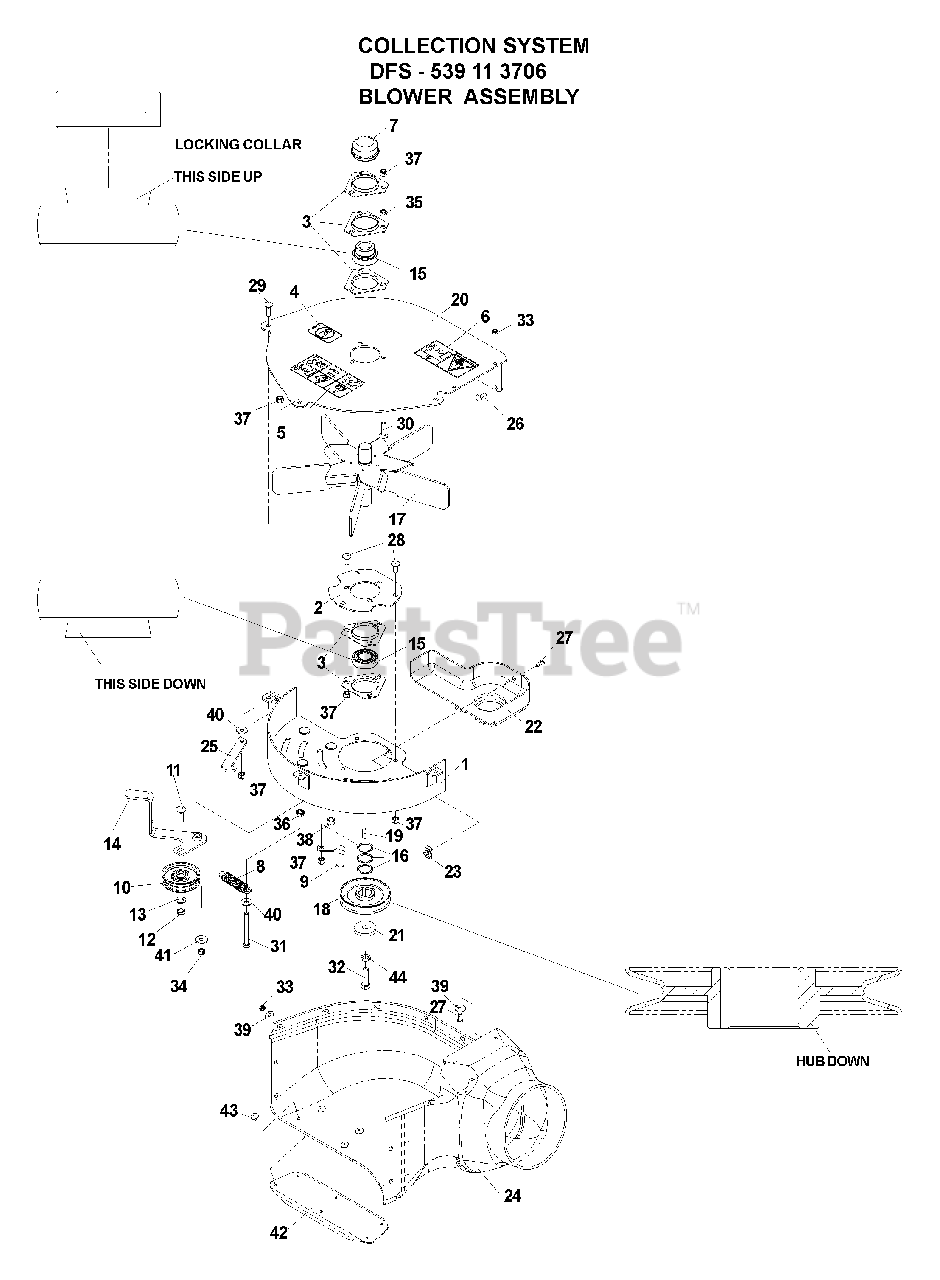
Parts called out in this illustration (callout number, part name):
1	FLOOR WELDMENT
2	BEARING PLATE
4	DECAL, NO STEP
5	DECAL, WARNING
6	DECAL, SERVERING
7	GREASE CAP
9	BELT GUIDE
11	RHSNB, 3/8-16 X 1 1/4, GR5
12	NUT, 3/8-16, JAM NYLOC
13	WASHER, 3/8, SAE
16	BUSHING, MACHINE, 18 GA
17	FAN WELDMENT
19	KEY, 1/4 SQ. X 3/4
21	WASHER, HEAVY
22	PULLEY SHIELD
23	RETAINER, 1/4C, "U" TYPE
24	BLOWER HOUSING
25	KEEPER, IDLER
26	RHSNB, 1/4-20 X 3/4, GR2
27	SCREW, 1/4-20 X 5/8, BTN, SKT HD
28	RHSNB, 5/16 X 3/4
29	RHSNB, 5/16-18 X 1, GR5
30	RHSNB, 5/16C X 1 1/4
31	HCS, 5/16-18 X 2 3/4, GR5
32	HCS, 7/16-20 X 1 1/2, GR5
33	NUT, 1/4C, THIN NYLOC
34	NUT, 5/16C, CENTERLOCK
35	NUT, 5/16C
36	NUT, 5/16C
37	NUT, 5/16C, NYLOC
38	NUT, 3/8C, NYLOC
39	WASHER, 1/4
40	WASHER, 5/16
41	WASHER, 3/8
42	BLOWER SUPPORT
44	LOCKWASHER, 7/16
539113706	Blower Assembly (DFS)
